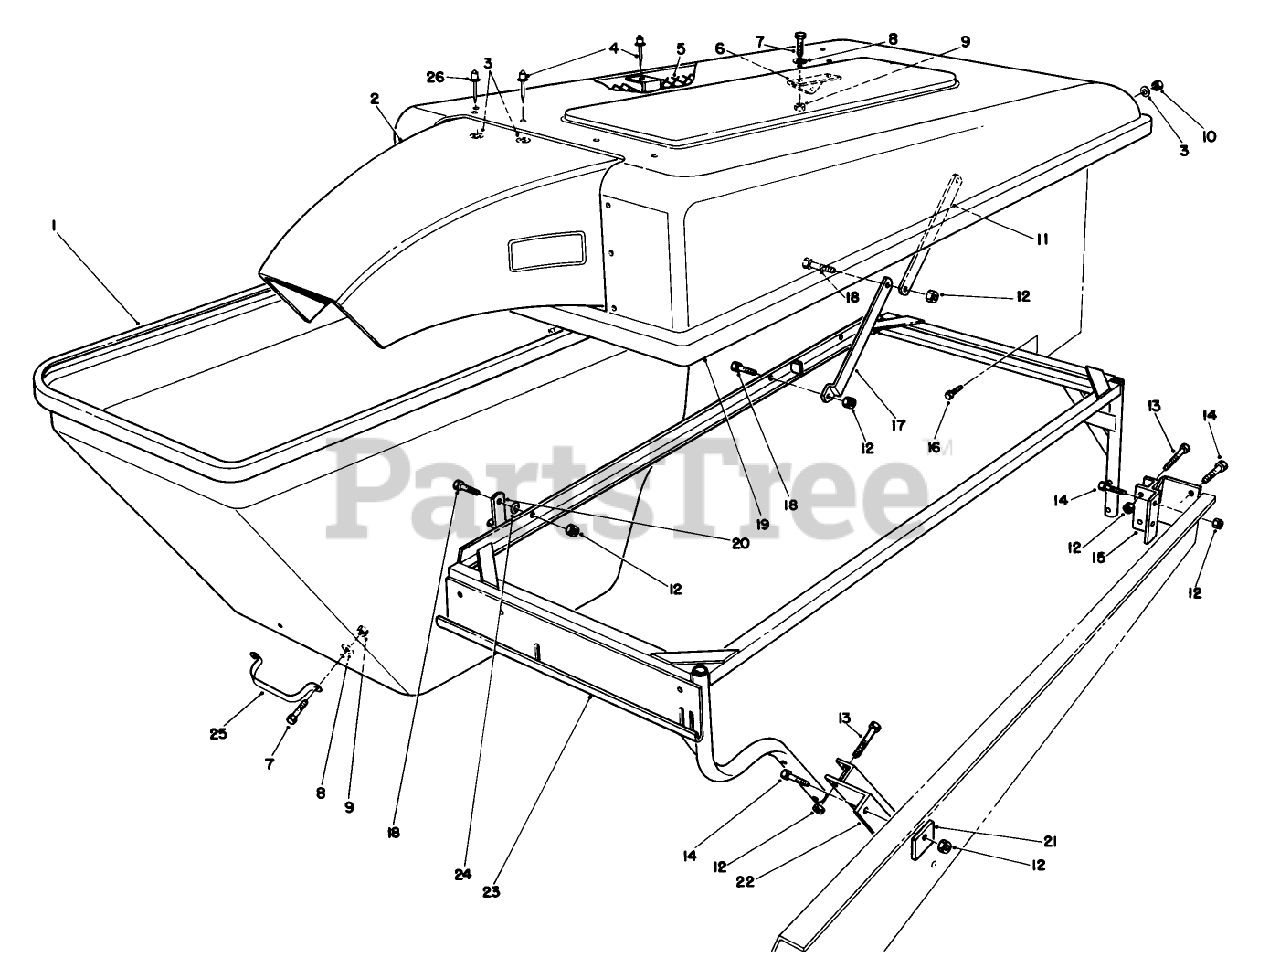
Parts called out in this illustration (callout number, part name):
1	BAGGER HOPPER
2	BAGGER SNOUT
3	WASHER-FLAT
5	Bagger Screen
6	Pivot
7	SCREW-HH
8	WASHER-FLAT
9	NUT-LOCK, NI
10	NUT-LOCK, NI
11	Link
12	NUT-LOCK, NI
13	SCREW-HH
14	SCREW-HH
15	Bracket-Rear
17	Link-Bag
18	SCREW-HH
19	Hood-Bagger
20	Latch-Hopper
21	Plate-Reinforcing
22	Bracket-Front
23	HOPPER FRAME WA
24	WASHER-SPRING
25	Handle
26	RIVET-POP
